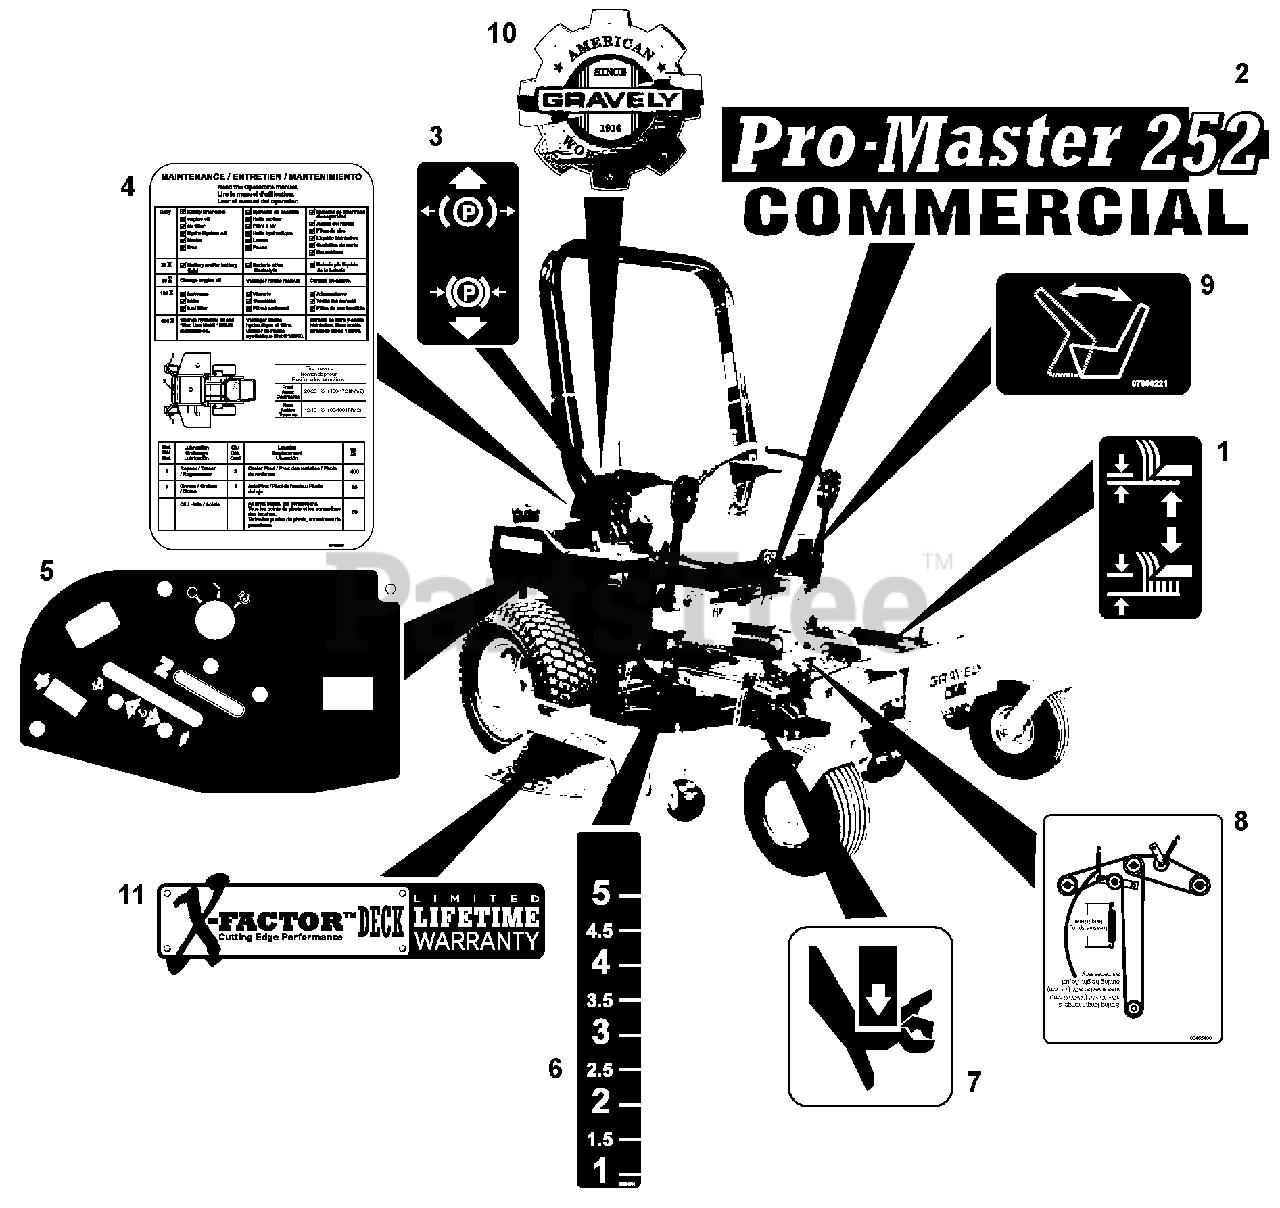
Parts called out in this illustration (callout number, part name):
1	Decal, Lift Lever (992213, 217, 219)
2	Decal, Pro-Master 252 (992212)
3	Decal, Parking Brake Lever
4	Decal, Maintenance Instructions
5	Decal, Control Panel
6	Decal, Height of Cut (992213, 217, 219)
7	Decal, Pinch Point (992213, 217, 219)
8	Decal, Belt Diagram (992210, 212, 213, 217)
9	Decal, Seat Release
10	Decal, Heritage Large
11	Decal, X-Factor Deck
